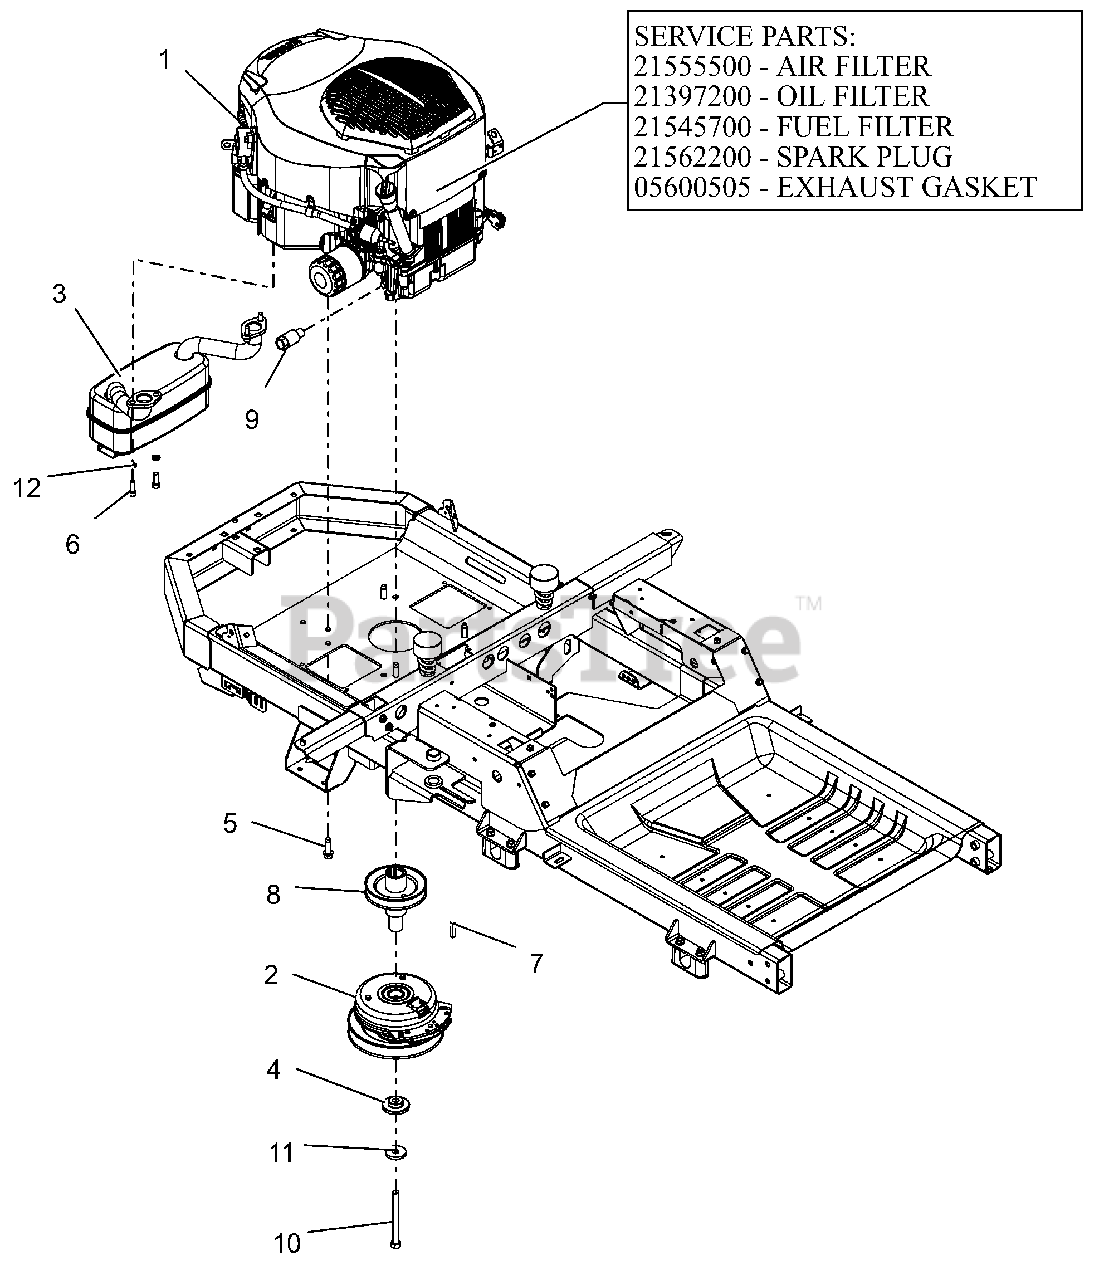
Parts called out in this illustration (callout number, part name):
1	ENGINE, KOHLER 24HP TWIN
1	AIR CLEANER, KOHLER
1	FILTER, OIL - KOH CV20
1	FILTER-FUEL KOHLER COURAGE PRO
1	PLUG, SPARK (RFI)
1	GASKET, MUFFLER KOHLER TWIN
2	CLUTCH,105FTLB MONOPOLE 6.83"
3	MUFFLER - KOHLER
4	BSHG-FLG .469X1.06X.574X2.0
5	SCR,TAP .375-16X1.25HWH TR ZCC
6	SCR, SKH .312-18X.875 GR8 ZCC
7	KEY-SQ .25 X 1.25 X .25 SAE
8	WLDMT, DRIVE SHEAVE-X
9	DRAIN, OIL
10	BLT, HEX .44-20X4.50 G8 ZCC NT
11	WASHER, 7/16" SPRING DISK
12	WSHR,LK-REG .312X.078 ZCC
